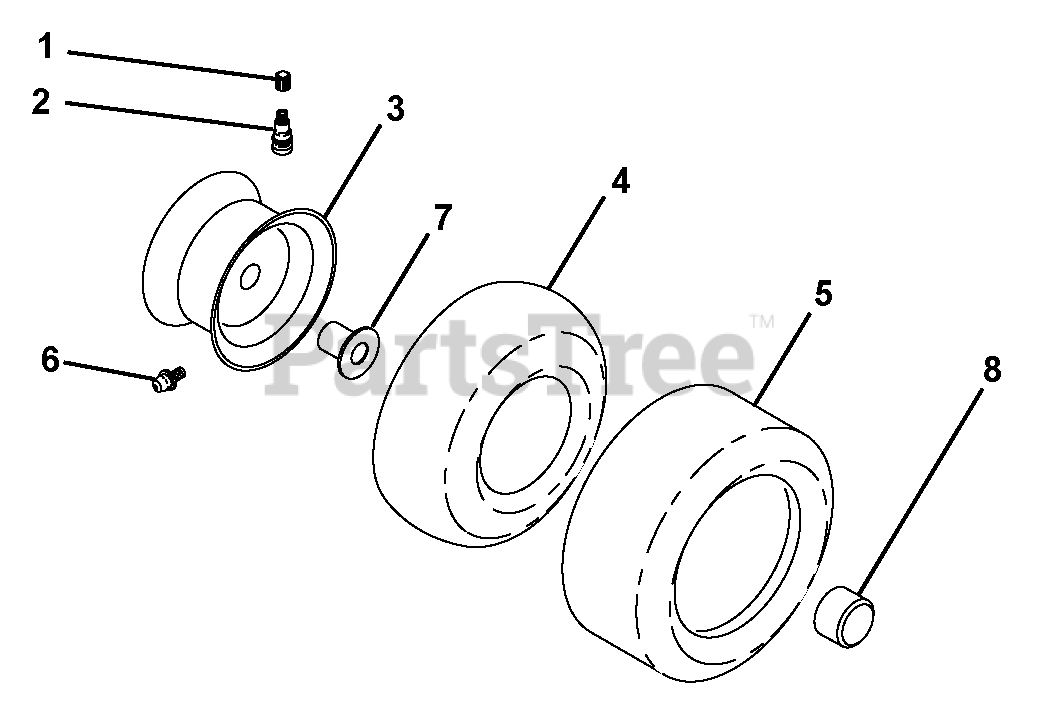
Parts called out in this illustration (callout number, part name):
1	Cap, Valve, Tire
2	Stem, Valve
3	Rim Assembly, Front
3	Rim Assembly, Rear
4	Tube, Front (Service Item Only)
4	Tube, Rear (Service Item Only)
5	Tire, Front
5	Tire, Rear
6	Fitting, Grease
7	Bearing, Flange (Front Wheel Only)
8	Cap, Hub, Axle Blk.
8	Sealant, Tire (10 oz. Tube)
